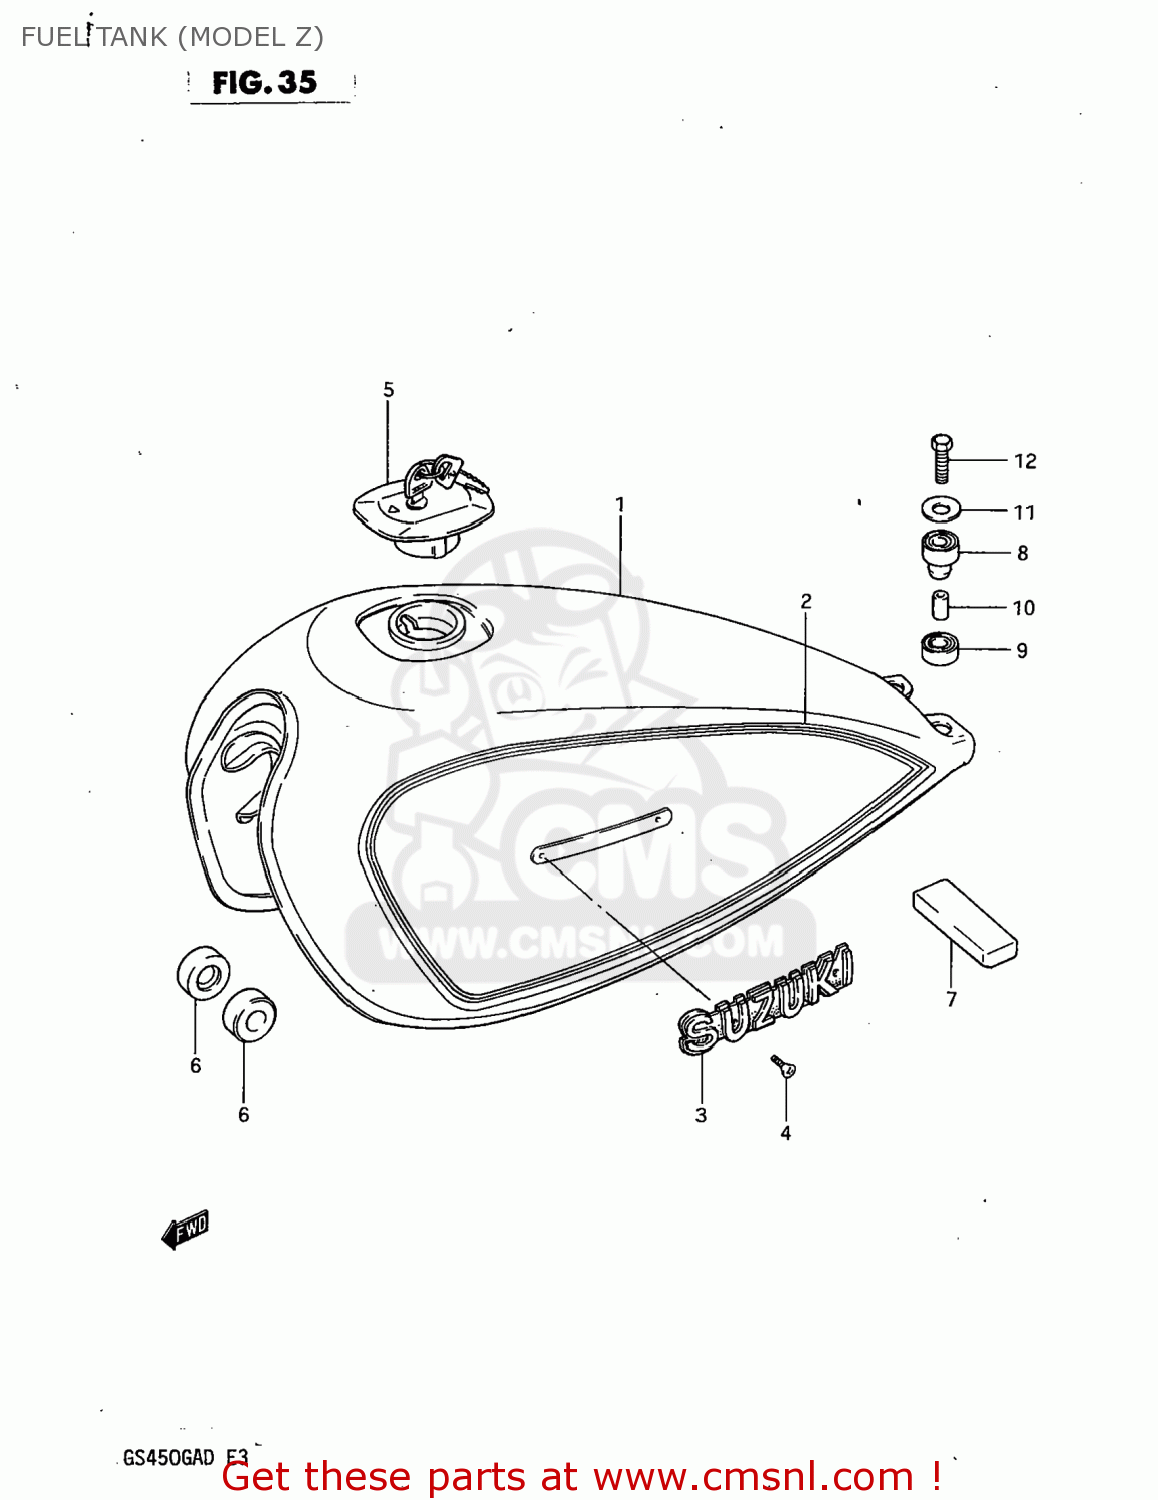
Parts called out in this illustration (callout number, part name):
1	TANK ASSEMBLY,FUEL
2	TAPE SET,FUEL TANK
3	EMBLEM,FUEL TANK
4	SCREW 3X6
5	CAP SET,FUEL TANK
6	CUSHION
7	CUSHION
8	CUSHION
9	CUSHION
10	SPACER (6.4X9X20)
11	WASHER (6.5X24X1.6)
12	BOLT
